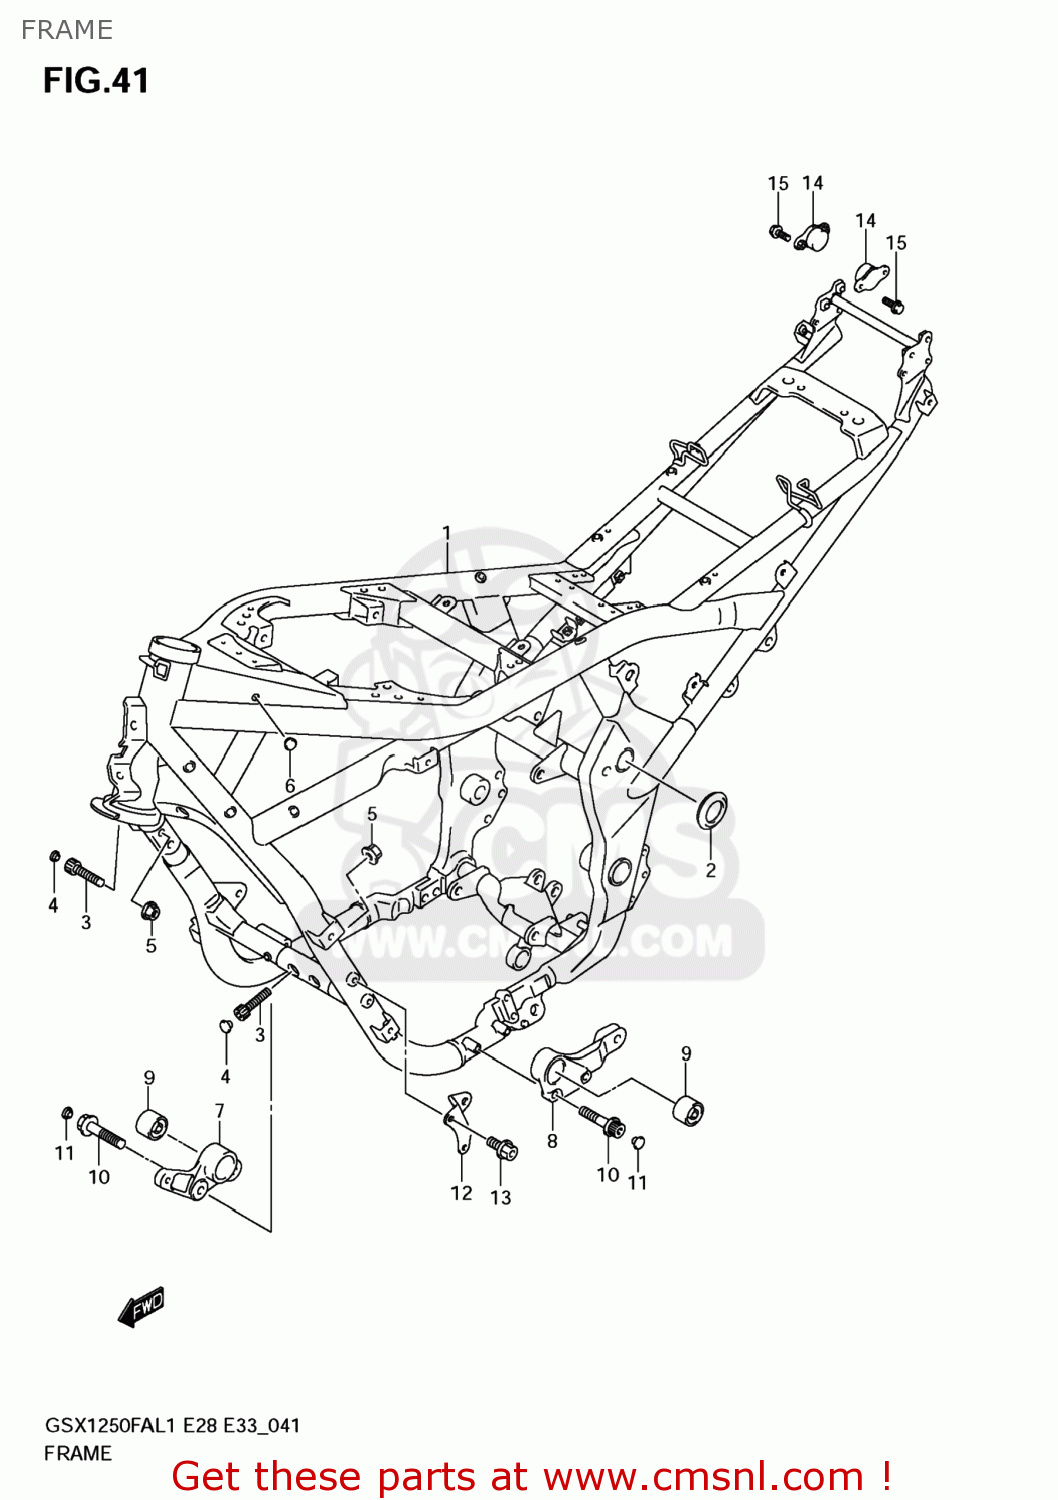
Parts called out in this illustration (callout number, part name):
1	FRAME(BLACK)
2	CAP,FRAME PIVOT
3	BOLT(10X37)
4	CAP(OD:12)
5	NUT
6	PLUG(OD:17)
7	BRACKET,ENGINE MOUNTING NO.2,R
8	BRACKET,ENGINE MOUNTING NO.2,L
9	BUSH,ENG MOUNTING NO.2
10	BOLT(8X28)
11	CAP(OD:10)
12	BRACKET,ENGINE MOUNTING FR
13	BOLT
14	DAMPER,FRAME
15	BOLT
